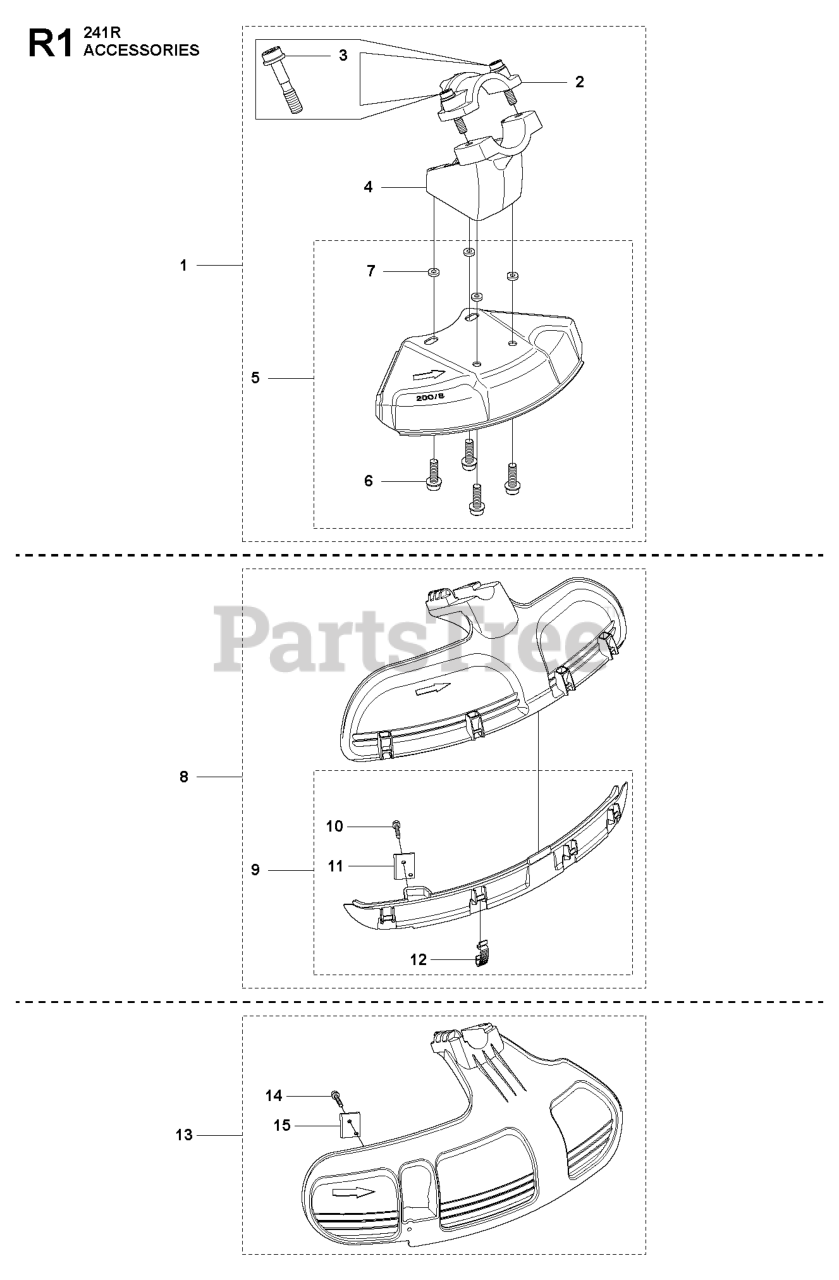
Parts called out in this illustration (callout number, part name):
1	ADAPTER
2	CLAMP
3	SCREW IHSCFMO
4	ADAPTER
5	BLADE GUARD
7	LOCKING NUT
8	COMBI PROTECTOR
9	SPLASH GUARD
11	LINE CUTTER
12	BUCKLE
15	LINE CUTTER
